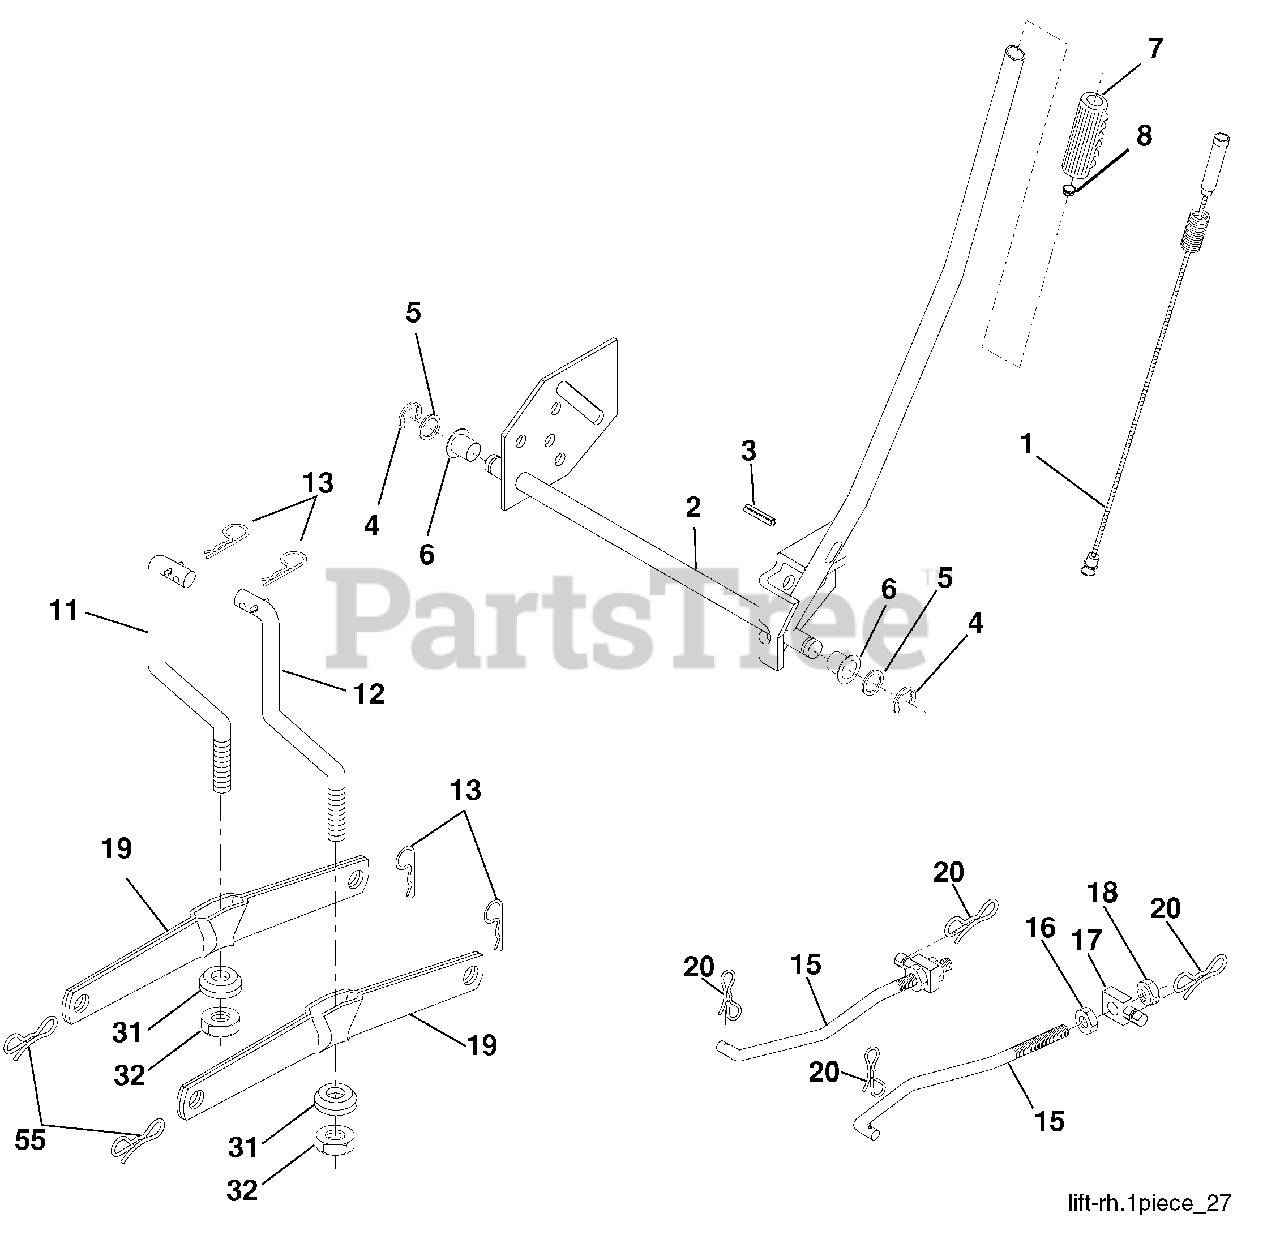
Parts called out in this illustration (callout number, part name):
1	Wire Asm Inner/Sprg w/plunger
2	Shaft Asm Lift RH
3	Pin Groove 1 500 Zinc
4	E Ring #5133-62
5	Washer 21/32 x 1 x 21 Ga.
6	Bearing Nylon Blk 629 Id
7	Grip Handle Bicycle Matte Blk
8	Button Plunger Black
11	Link Lift LH Fixed Length
12	Link Lift RH Fixed Length
13	Retainer Spring
15	Link Front
16	Nut Jam Hex 1/2-13 unc
17	Trunnion
18	Nut Lockw/Wsh 1/2-13 unc
19	Arm Suspension Rear
20	Pin Cotter 7/16 Bow Tie Lock
31	Bearing Pvt Lift
32	Nut Crownlock 3/8-24
55	Pin Cotter 5/16 Bow Tie Lock
